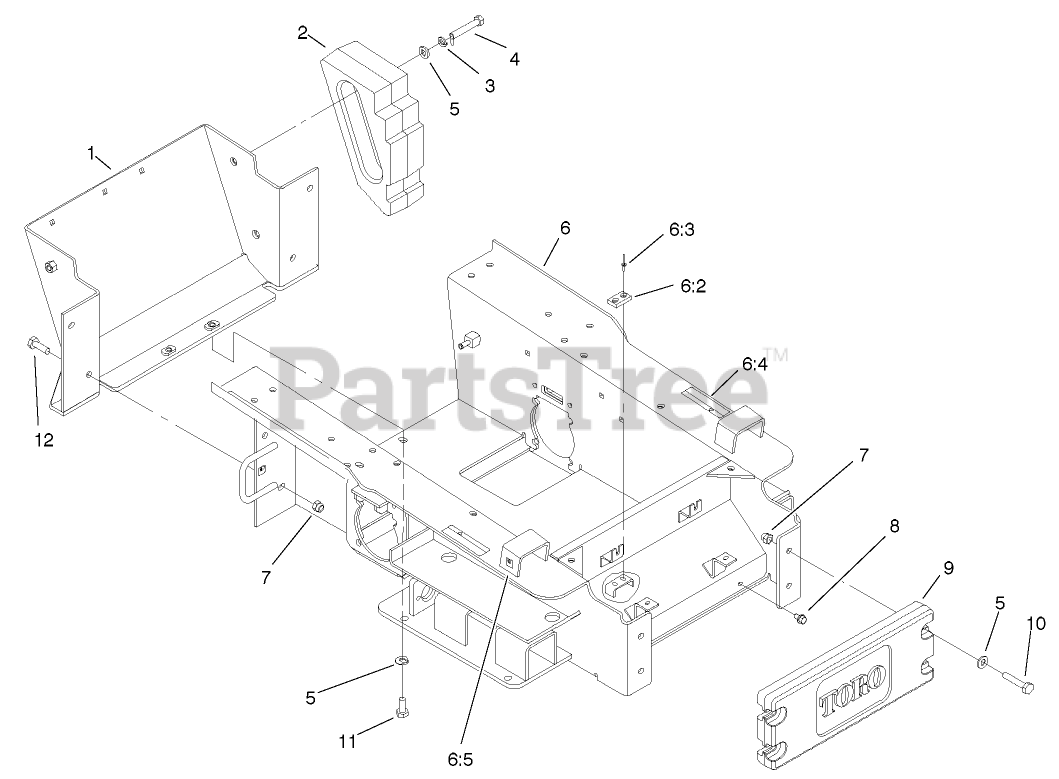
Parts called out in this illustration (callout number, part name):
1	REAR FRAME COVER ASM
2	COUNTERWEIGHT-REAR
3	WASHER-LOCK
4	SCREW-HH
5	WASHER-FLAT
6	MAIN CHASSIS ASM
6:2	PAD-SUPPORT
6:3	RIVET-POP
6:4	DECAL-PINCH
6:5	DECAL-POINT, LIFT
7	NUT-LOCK, NI
8	SCREW-HWHTF
9	COUNTERWEIGHT-FRONT
10	SCREW-HH
11	SCREW-HH
12	SCREW-HH
